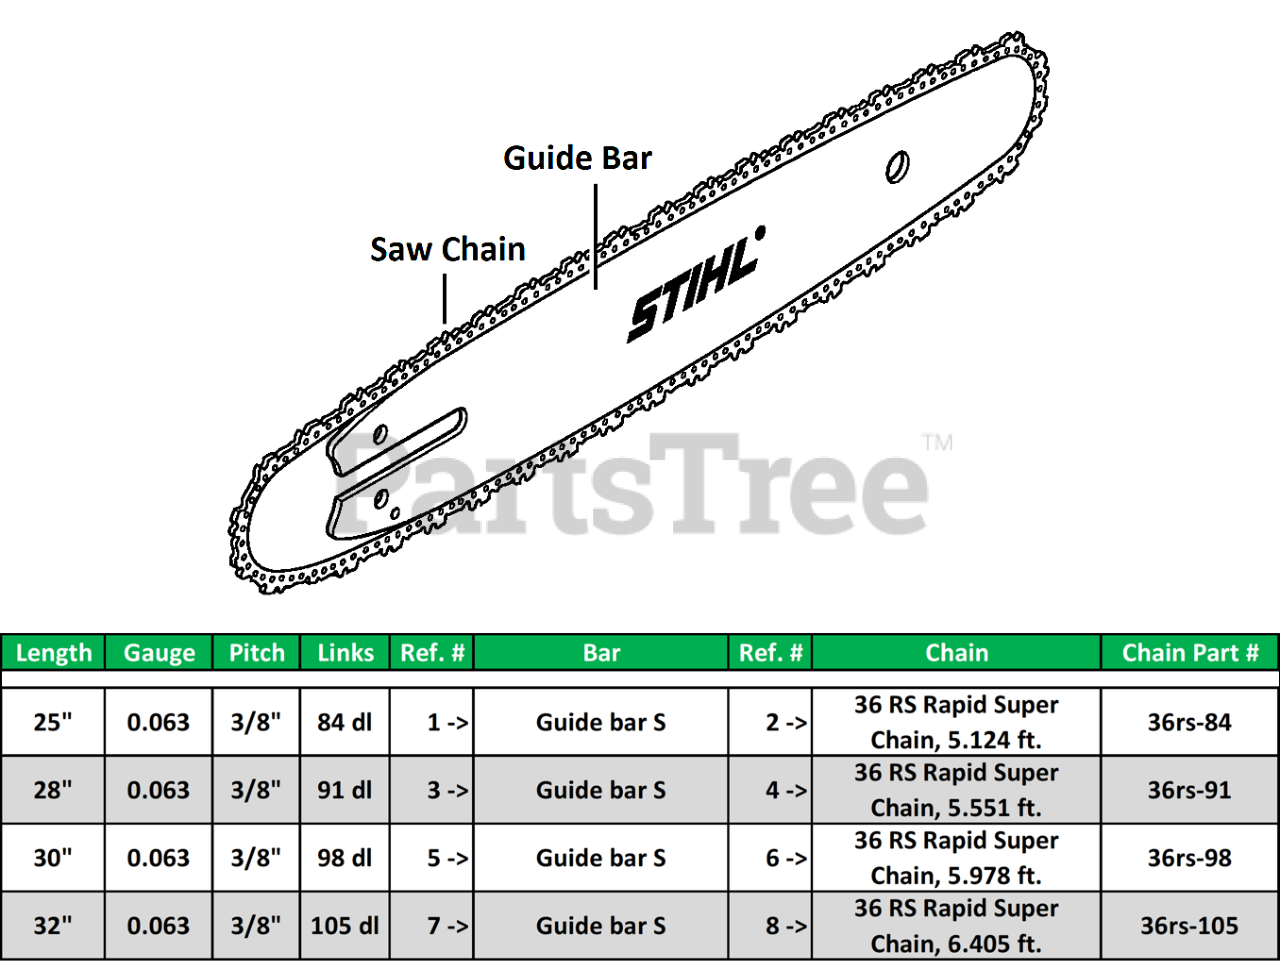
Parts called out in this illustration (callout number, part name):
1	Guide bar S 63cm/25" 1,6mm/0.063" 3/8"
2	36 RS Rapid Super Chain, 5.124 ft.
3	Guide bar S 71cm/28" 1,6mm/0.063" 3/8"
4	36 RS Rapid Super Chain, 5.551 ft.
5	Guide bar S 75cm/30" 1,6mm/0.063" 3/8"
6	36 RS Rapid Super Chain, 5.978 ft.
7	Guide bar S 80cm/32" 1,6mm/0.063" 3/8"
8	36 RS Rapid Super Chain, 6.405 ft.
